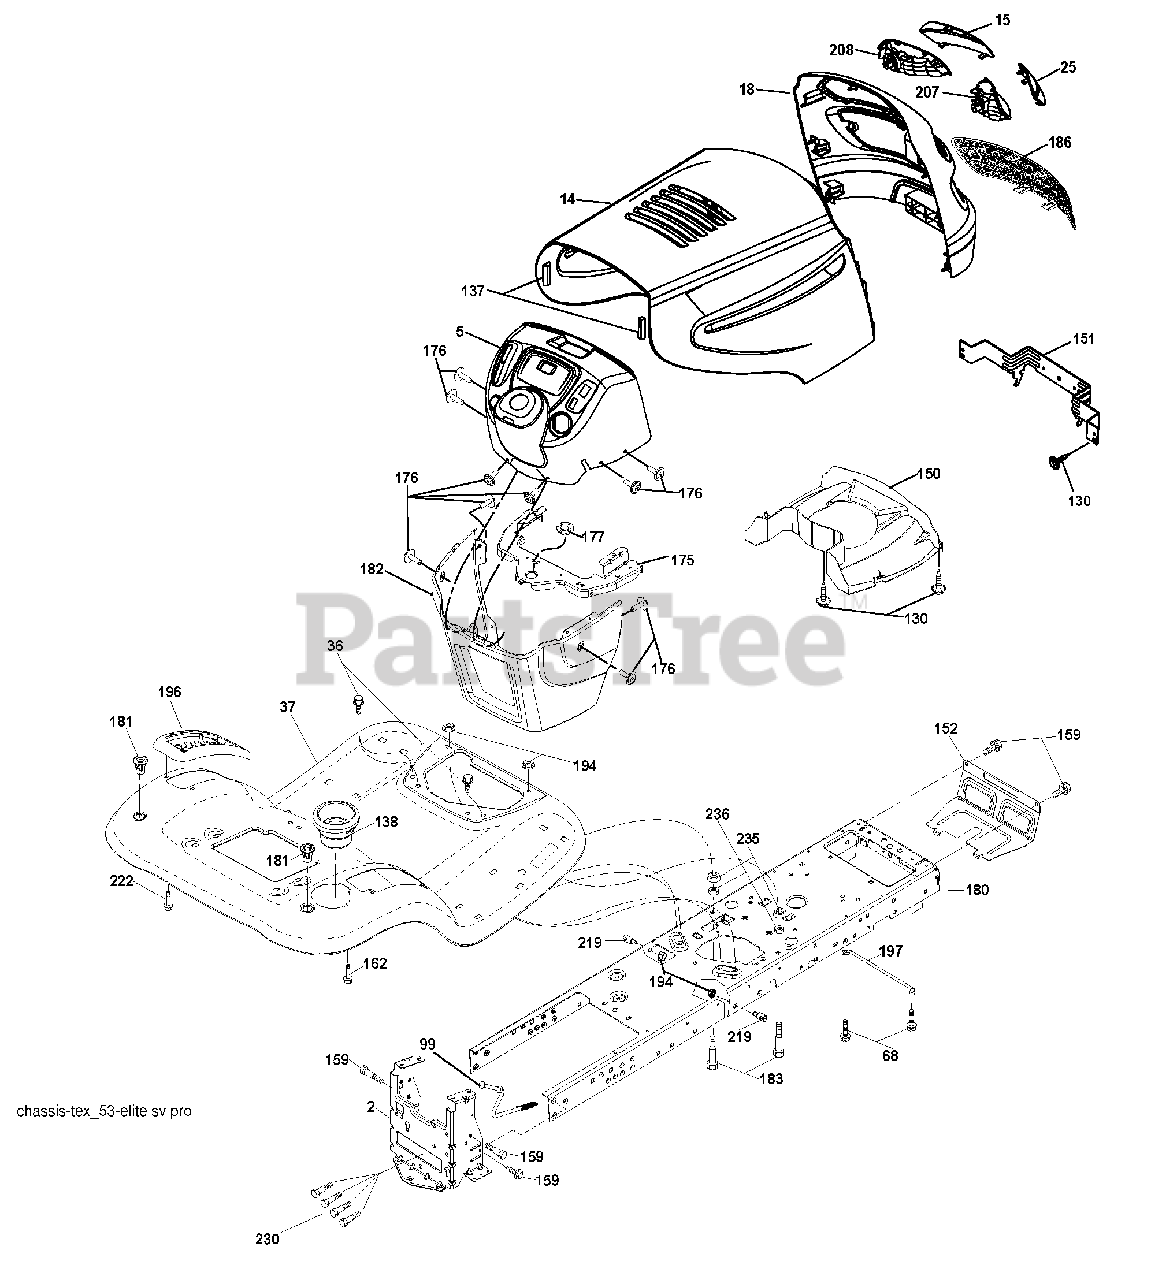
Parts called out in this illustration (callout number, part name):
2	Drawbar
5	Dash
14	Hood
15	Lens Grille LH
18	Grille
25	Lens Grille RH
36	Screw 5/16-18 x 3/4
68	Screw Thdrol 5/16-18 x 1/2
99	Rod Bypass
130	Screw 10 x 3/4 Single Lead-Hex
137	Bumper Hood
138	Cupholder
150	Duct Heat Hood
151	Bracket Pivot
152	Shield Browning/Debris
159	Screw Hexwsh Thdrol 3/8-16 x 3/4
162	Screw Hex Wsh Hi-Lo 1/4 x 1/2
175	Crossmember
176	Screw 10-24 x 5/8 Wshd Qdrx
177	Bushing Steering
181	Bushing Mtg. Fender Crgo.
182	Dash Lower
183	Bolt Fin Hex 5/16-18 x 1-1/4
194	Nut Lock Hex Flange 5/16-18
196	Console Asm. Deck Lift
197	Rod Pivot Chassis
207	Bezel Grille RH
208	Bezel Grille LH
219	Stud Fastener
222	Screw Thd Roll 1/4-20 x 5/8
230	Bolt Shoulder 5/16-18
235	Spacer Fender
236	Nut center Lock 5/16-18
